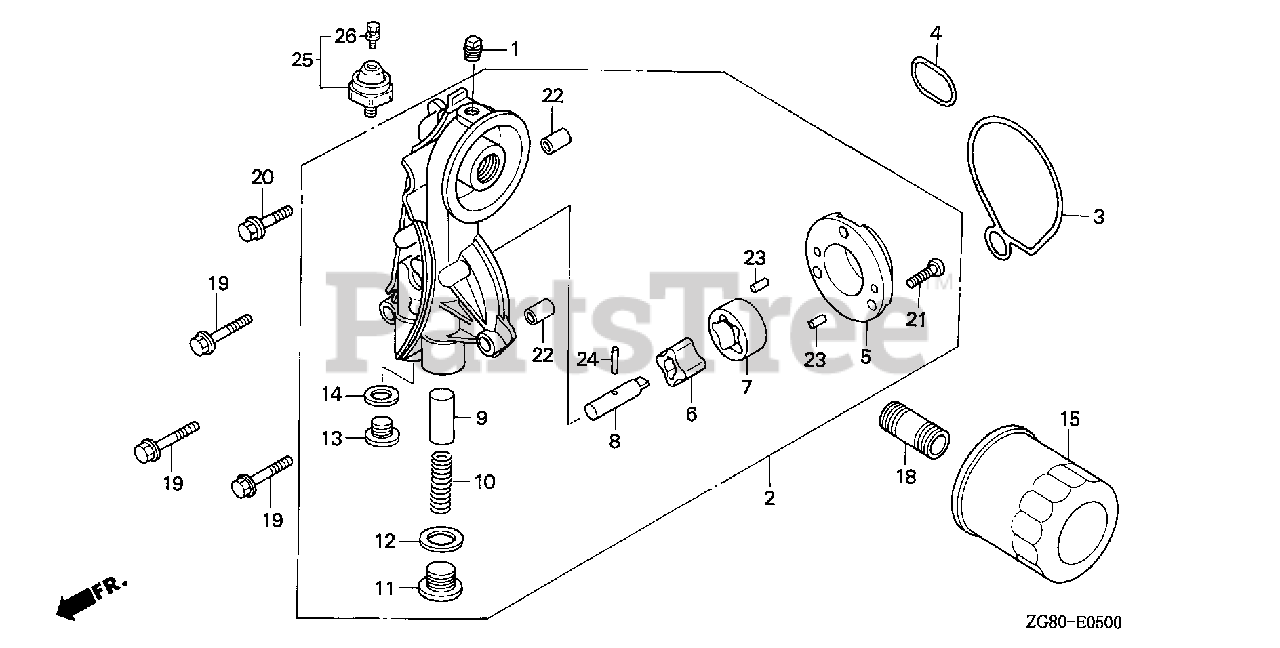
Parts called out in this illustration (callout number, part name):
1	BOLT, SEALING
2	PUMP ASSY., OIL
3	GASKET, OIL PUMP
4	GASKET, OIL PUMP (B)
5	COVER, OIL PUMP
6	ROTOR, OIL PUMP (INNER)
7	ROTOR, OIL PUMP (OUTER)
8	SHAFT, OIL PUMP
9	VALVE, RELIEF
10	SPRING, RELIEF VALVE
11	BOLT, SEALING (18MM)
12	WASHER, SEALING (18MM)
13	BOLT, SEALING (14MM)
14	WASHER, SEALING (14MM)
15	FILTER, OIL (TOYO ROKI)
15	FILTER, OIL (DENSO)
18	HOLDER, OIL FILTER
19	BOLT, FLANGE (6X32) (CT200)
20	BOLT, FLANGE (6X25) (CT200)
21	SCREW, PAN (6X14)
22	PIN, DOWEL (8X14)
23	PIN, DOWEL (5X8)
24	ROLLER (3X15.8)
